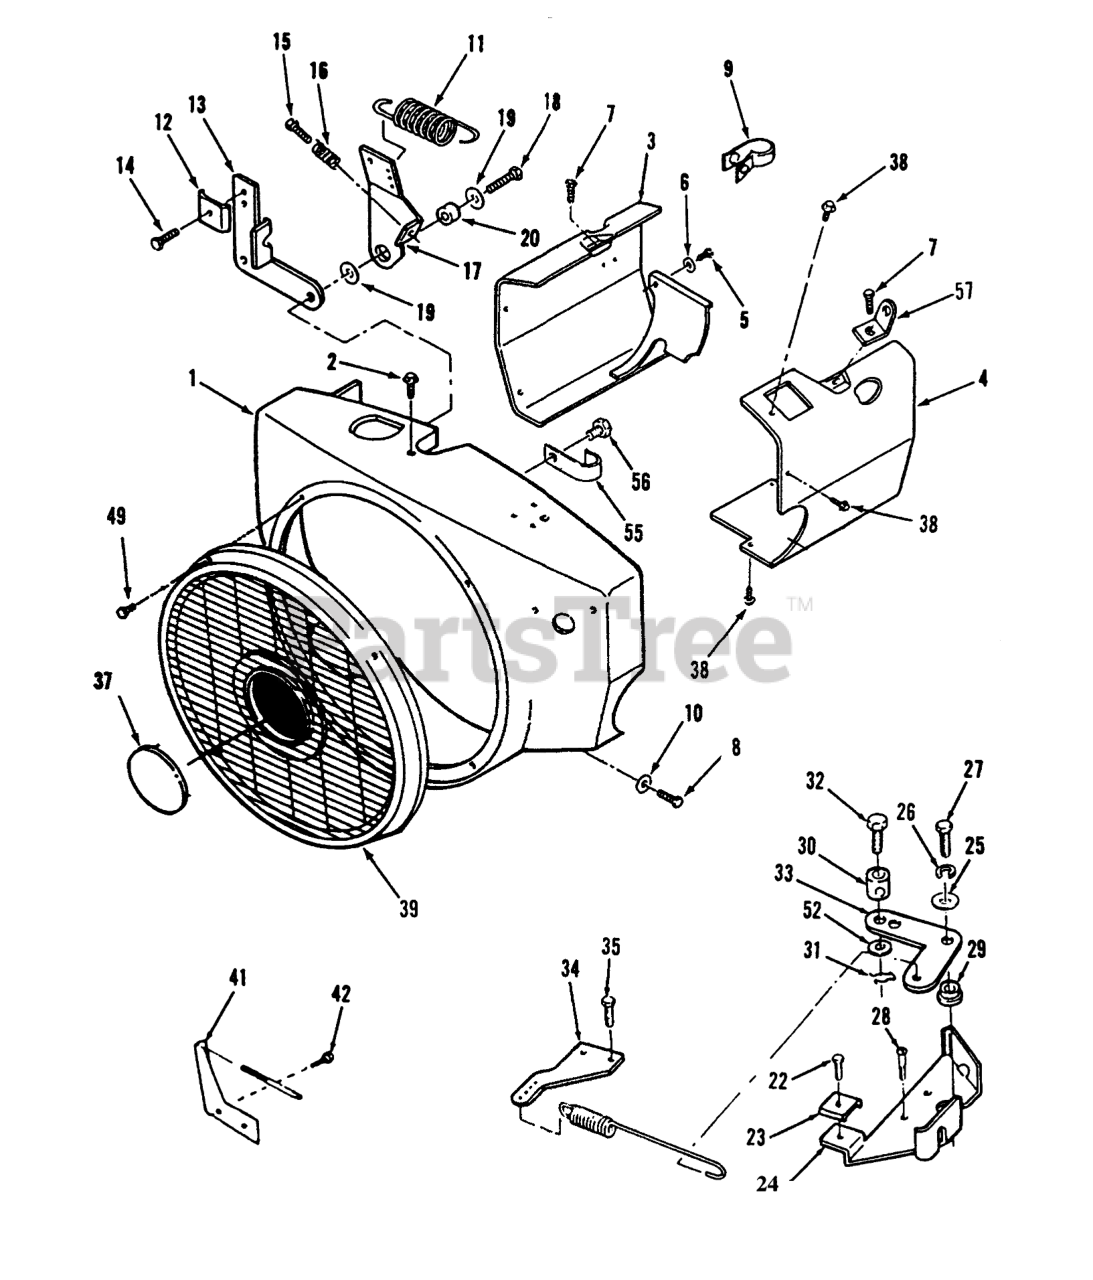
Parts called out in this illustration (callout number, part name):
1	BLOWER-HOUSING
2	HEX HD CAPSCREW
3	CYLINDER AIR HSG L H
4	Housing, Cylinder Air-RH
5	SCREW-HH
6	WASHER-FLAT
7	SCREW-HWH
8	SCREW-HH
9	Clamp
10	WASHER-FLAT
11	SPRING
13	Bracket
14	SCREW-TAPPING
15	SCREW-TAP
16	SPRING
17	Arm, Governor Control Without Swivel-Zinc Plated
19	WASHER-FLAT
20	BUSHING
22	SCREW-HWH
24	BRKT-GOVERNOR CONTRL
25	WASHER-FLAT
26	Washer-Lock
27	Bolt
28	HEX HD CAP SCREW
29	BUSHING-GOV CONTROL
30	BUSHING
31	PIN-COTTER
32	Bolt
33	LINK-GOV CONTROL
34	ADAPTER-GOV ARM
35	SCREW-TAPPING PAN HD
37	NAME-PLATE TORO LOGO
38	SCREW-HWH
39	GUARD-STATIONARY
41	BRACKET
42	SCREW-HWH
48	SCREW - THREAD CUTTING
49	SCREW-PAN HEAD
55	CLIP-WIRE
56	SCREW-HWH
57	BRACKET-LIFTING
